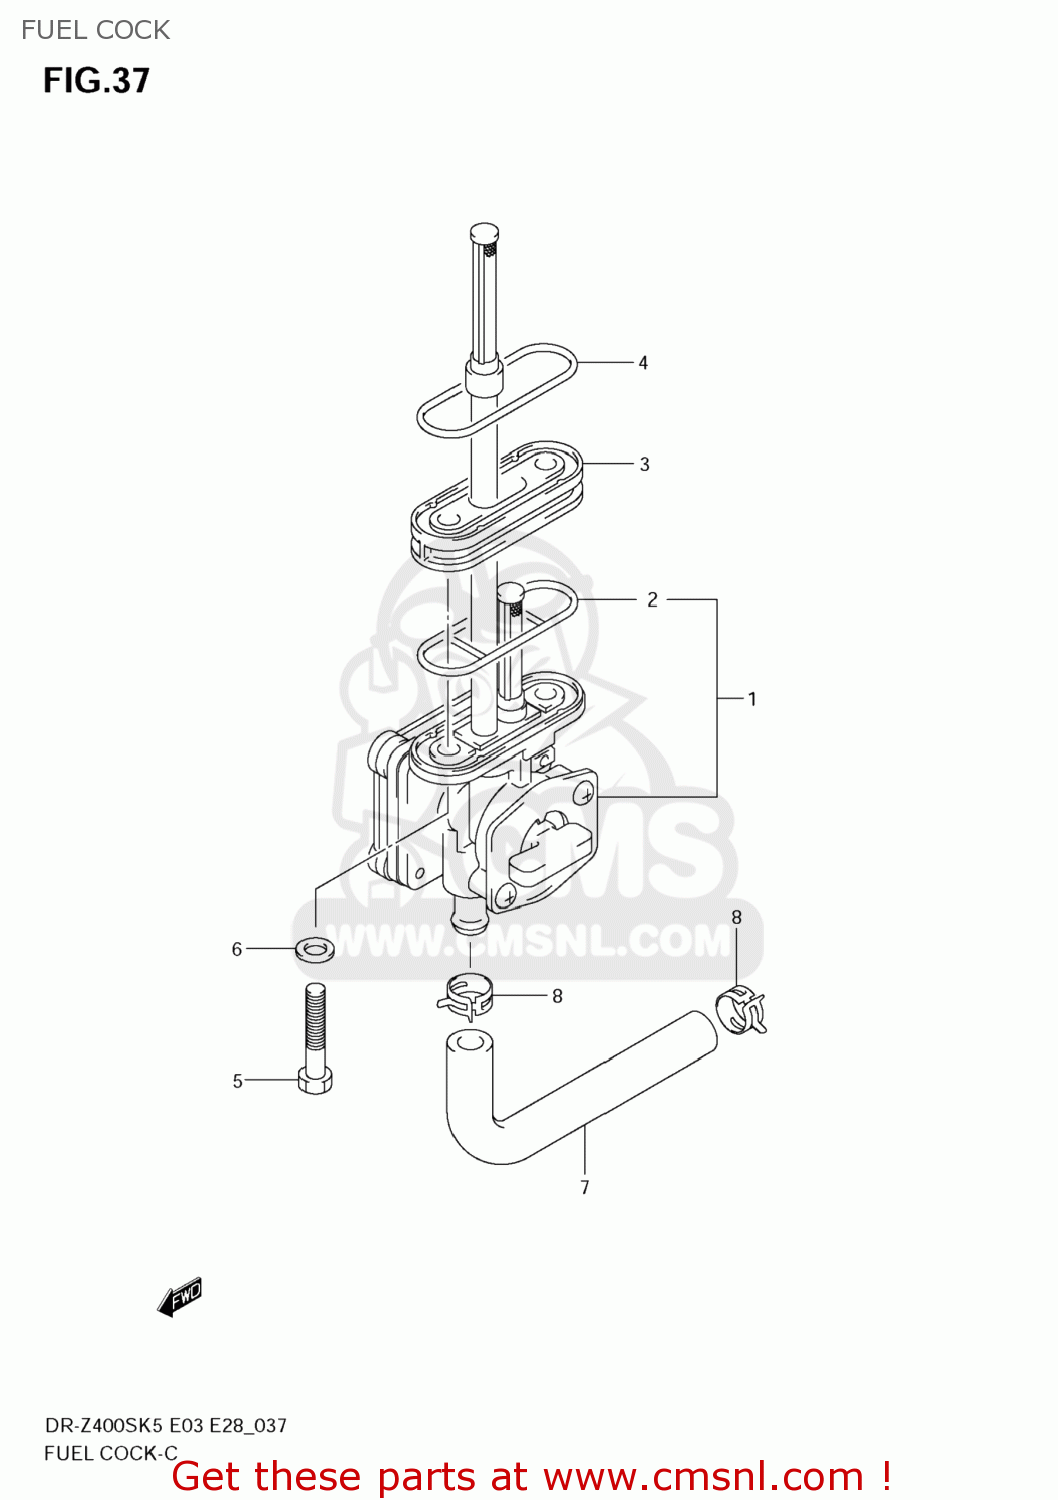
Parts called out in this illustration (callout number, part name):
1	COCK ASSY,FUEL
2	GASKET,JOINT (NAS)
3	SPACER,FUEL COCK
4	GASKET,FUEL COCK (NAS)
5	SCREW(6X30)
6	GASKET(6.4X11.5X0.8) (NAS)
7	HOSE,FUEL
8	CLIP
